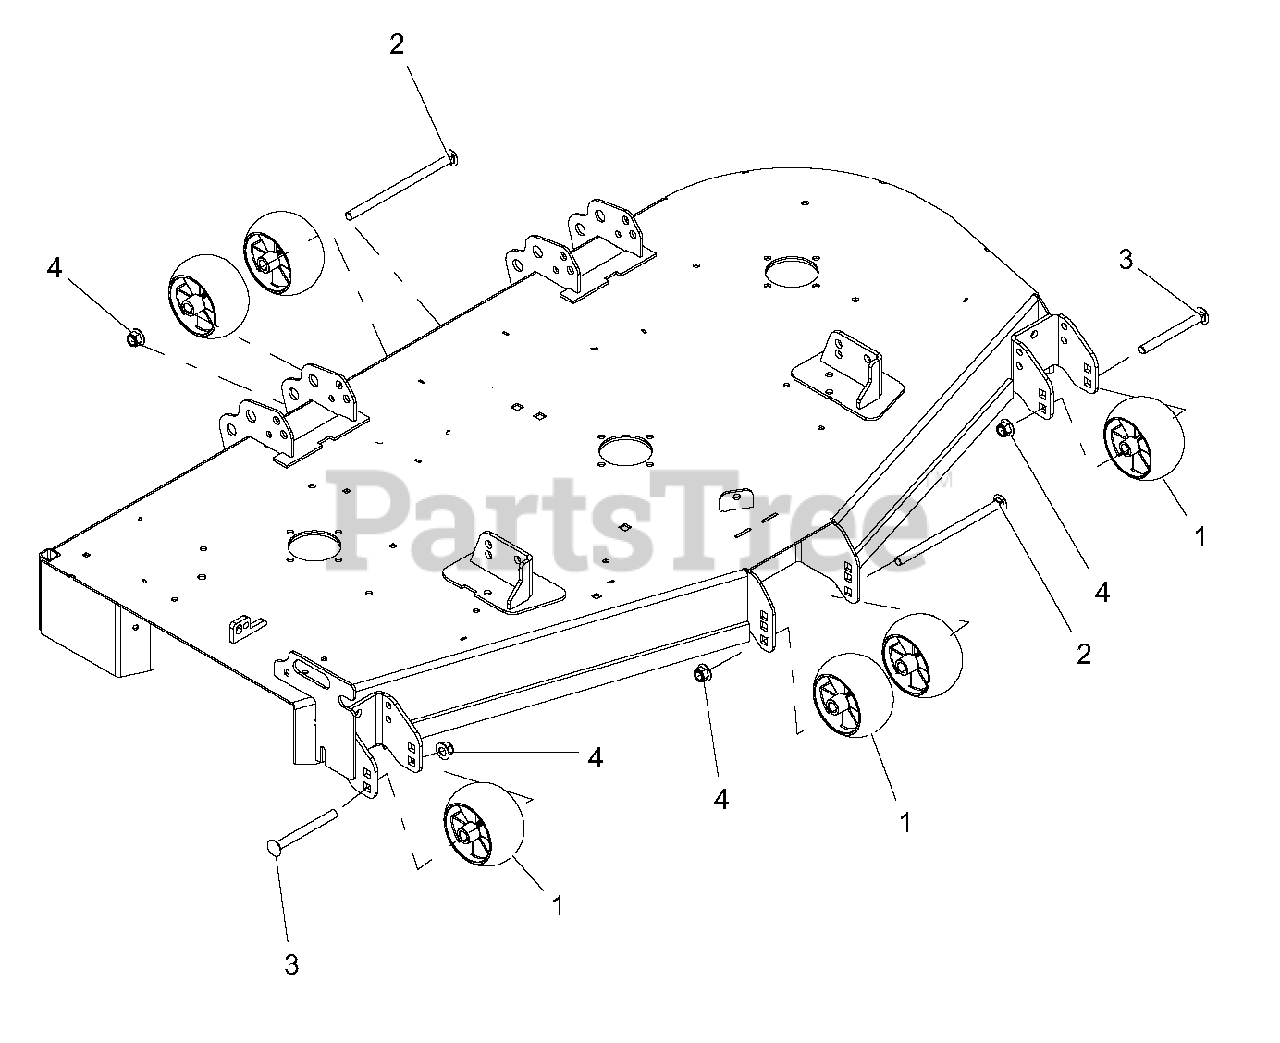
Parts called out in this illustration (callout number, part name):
1	ANTI-SCALP WHEEL - 5X3 CTR
2	@BLT-RDHDSQNK .50-13X8.50 Y
3	@BLT-RDHDSQNK .50-13X4.50 G5 YWZC
4	NUT-LK-NYL-FLG .50-13 YWZC
